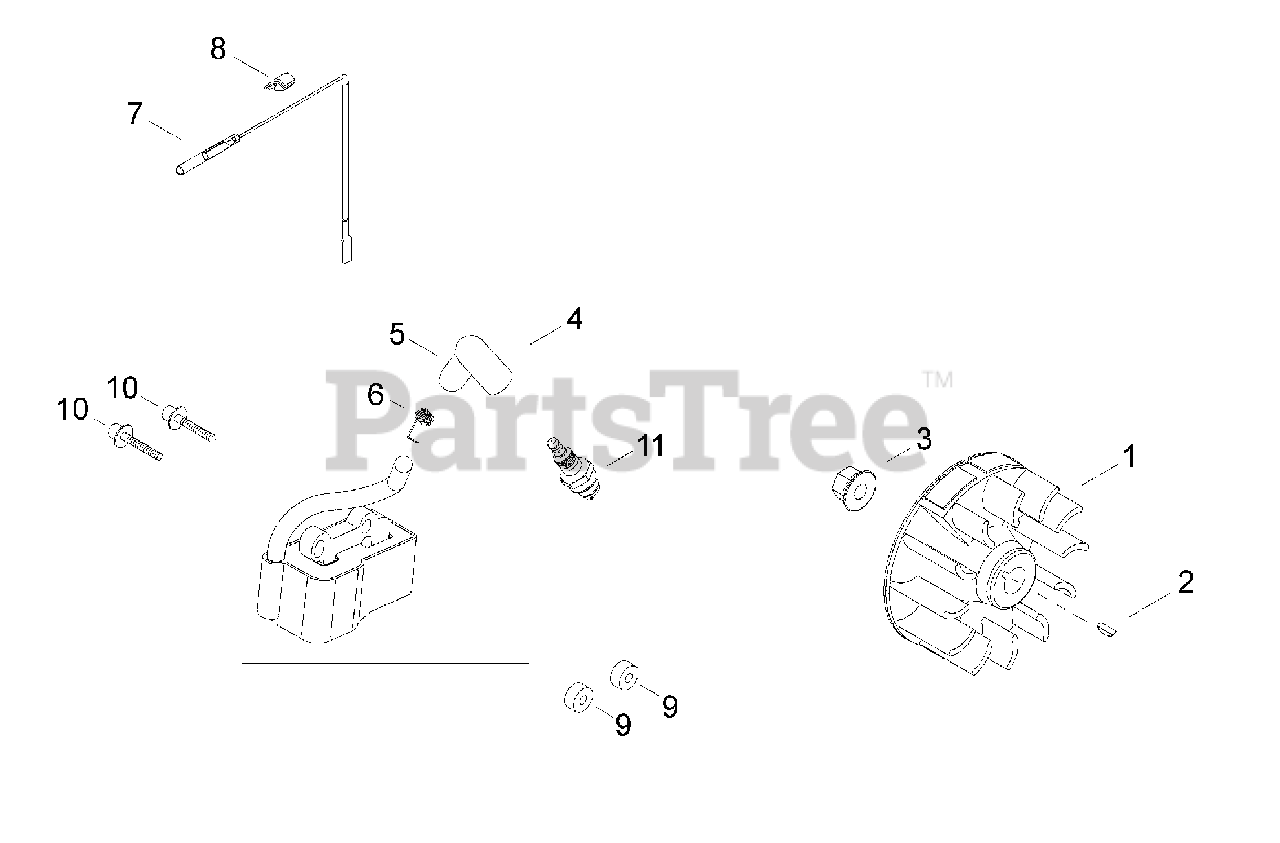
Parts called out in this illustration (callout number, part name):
1	FLYWHEEL
2	KEY, WOODRUFF 3×10
3	NUT M8
4	COIL ASSY, IGNITION
5	CAP, SPARK PLUG
6	TERMINAL, SPARK PLUG
7	LEAD - IGNITION
8	GROMMET, LEAD
9	INSULATOR 4.2×11×6
10	BOLT M4×26
11	SPARK PLUG - CMR5H
